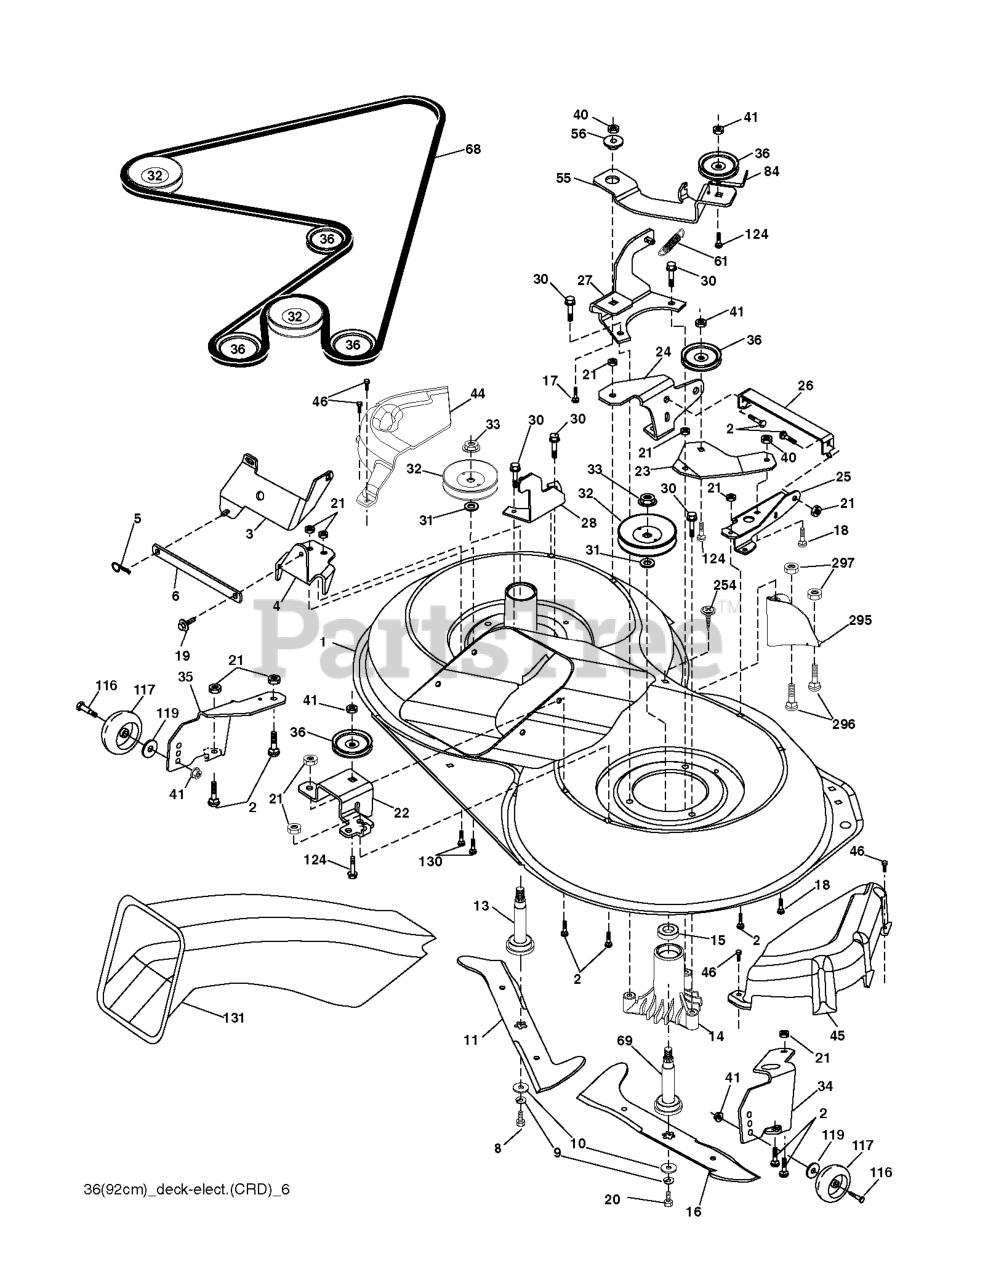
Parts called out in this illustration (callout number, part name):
2	RP BOLT 5/16-18 X3/4 ZN/YEL GR
5	RETAINER-SPRNG RB
6	BAR.SWAY.92.CRD
8	BOLT.3/8-24X1.25 GR8
9	LOCKWASHER
10	WASHER.BLADE
13	SHAFT ASM VENT
14	HOUSING.MANDREL.VENTED (MACHD)
17	BOLT.3/8-14X1.25
19	BOLT SHD 5/16-18
20	BOLT.3/8-24X1.25GR8. LHTHRD
21	LOCKNUT
26	SUPPORT
30	SCREW, WASHER HEAD
31	WASHER.SPACER.MANDREL
32	PULLEY, MANDREL
33	NUT.FLANGE.LOCK.TOP
36	PULLEY.IDLER.4.25
41	NUT LOCK FLG 3/8-16 UNC
45	COVER.MANDREL.RH.CRD
46	SCREW.1/4-20X5/8
55	ARM.IDLER.92 CRD.2006
56	SPACER.RETAINER.MOWER
61	SPRING.TENSION.BELT
68	BELT.DRIVE.92CM.CRD.2006
69	SHAFT.ASM.W/LWR.BRG.RH.THREAD
84	KEEPER, BELT IDLER
116	BOLT.SHOULDER.3/8-16X3-5/8.
117	RP WHEEL. GUAGE RALLY
119	WASHER
124	BOLT.3/8-16X1.50
130	BOLT.CARR.SQNK.5/16-18UNC.X3/4
131	CHUTE BAGGER
254	SCREW 3/8-16X1
296	BOLT
297	NUT CENTERLOCK
